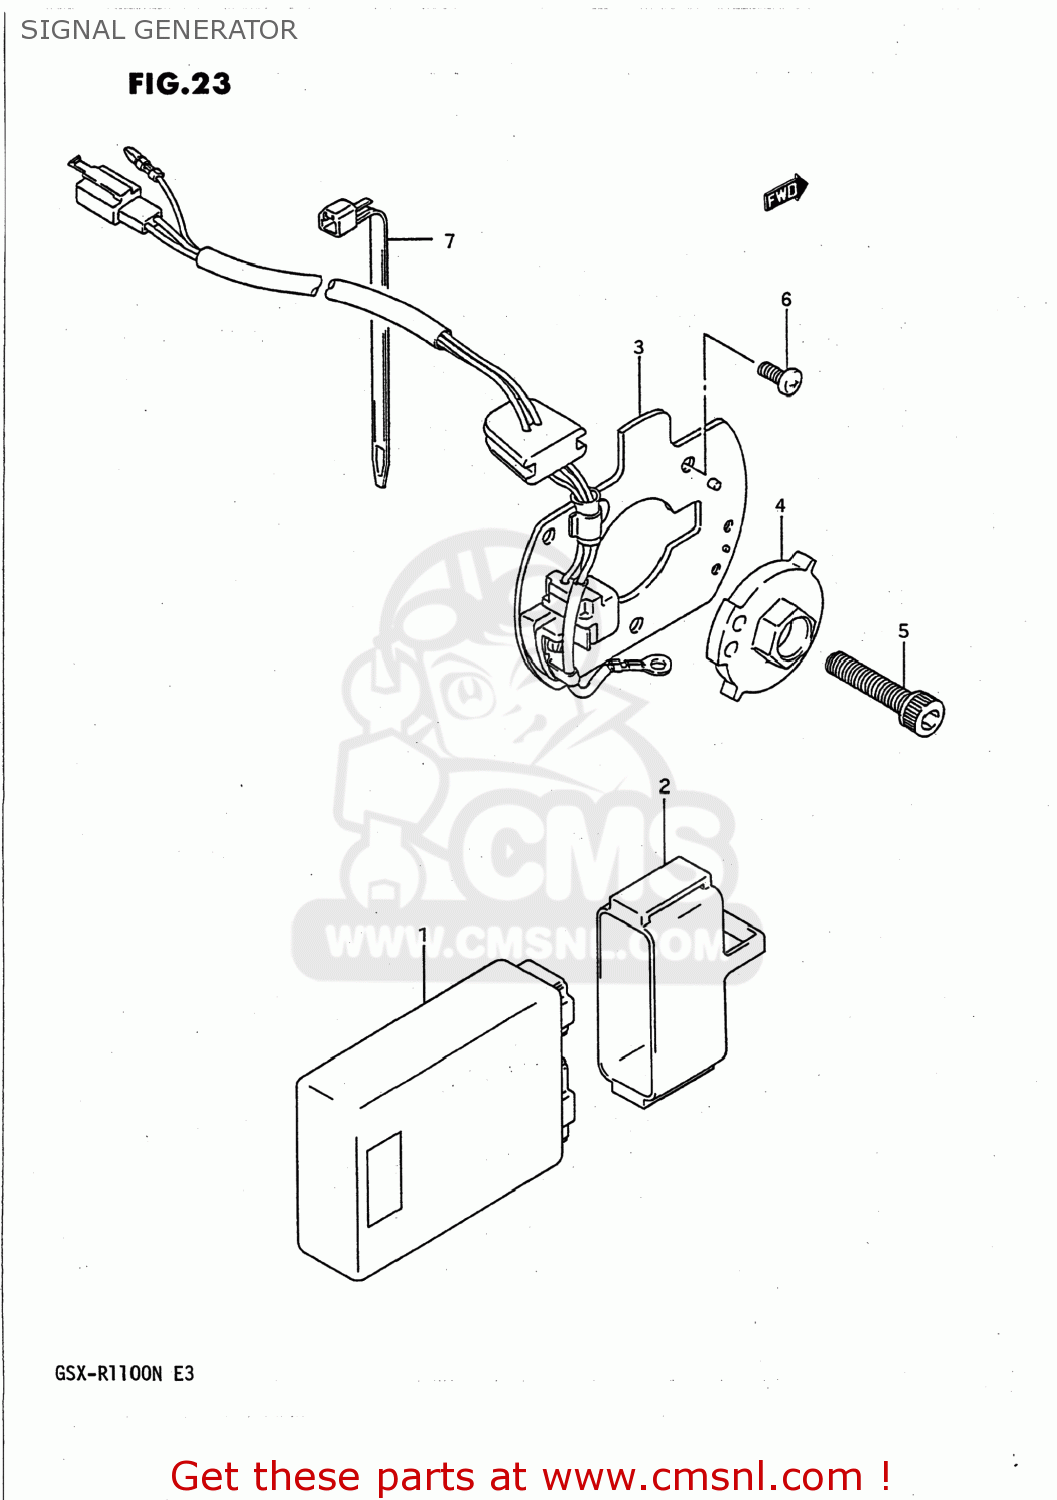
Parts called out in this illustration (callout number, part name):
1	IGNITOR
2	CUSHION,IGNITER
3	GENERATOR ASSY,SIGNAL
4	ROTOR,SIGNAL
5	BOLT
6	SCREW
7	CLAMP(L:125)
